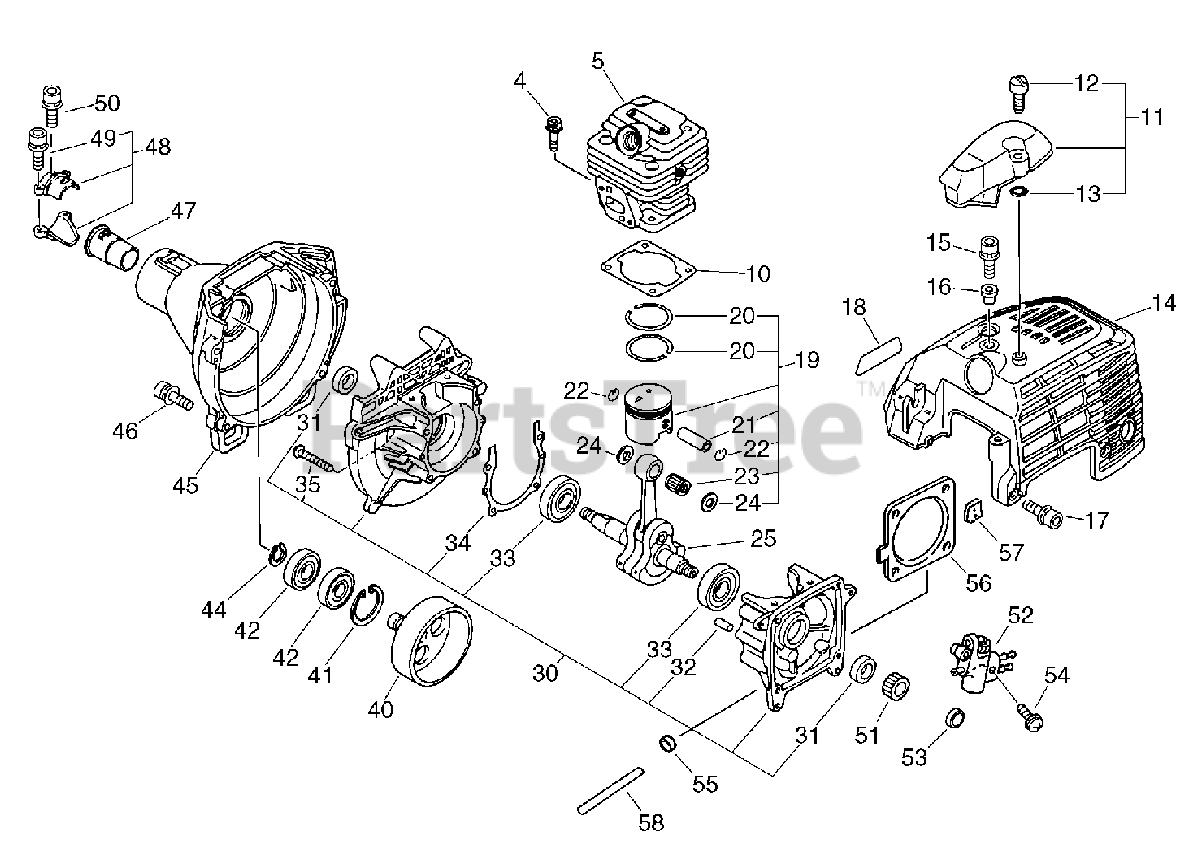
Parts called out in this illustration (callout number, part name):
4	BOLT 5×20
5	CYLINDER
10	GASKET, CYLINDER
11	GUARD KIT, TOP
12	THUMBSCREW M5×15.5
14	COVER, ENGINE
15	BOLT 5×20
17	BOLT 5×12
18	LABEL - MODEL
19	PISTON KIT
20	RING, PISTON
21	PIN, PISTON
22	RING, RETAINING
22	RING, SNAP
23	BEARING, NEEDLE 9
24	WASHER, THRUST
25	CRANKSHAFT ASSY
30	CRANKCASE KIT
31	SEAL, OIL 12
32	PIN, LOCATING 4×8
33	BEARING, BALL 6201
33	BEARING, BALL - 6201 C3
34	GASKET, CRANKCASE
35	BOLT 5×30
40	DRUM, CLUTCH
41	RING, SNAP 28
42	BEARING, BALL 6001
44	RING, RETAINING - 12
45	COVER, FAN
46	BOLT 5×20
47	CUSHION
47	CUSHION 28
48	HOLDER KIT
49	BOLT 5×25
50	BOLT 5×12
51	GEAR, WORM
52	AUTO-OILER ASSY
53	COLLAR 8
54	SCREW - 4×16
58	PIPE 2×4×115
